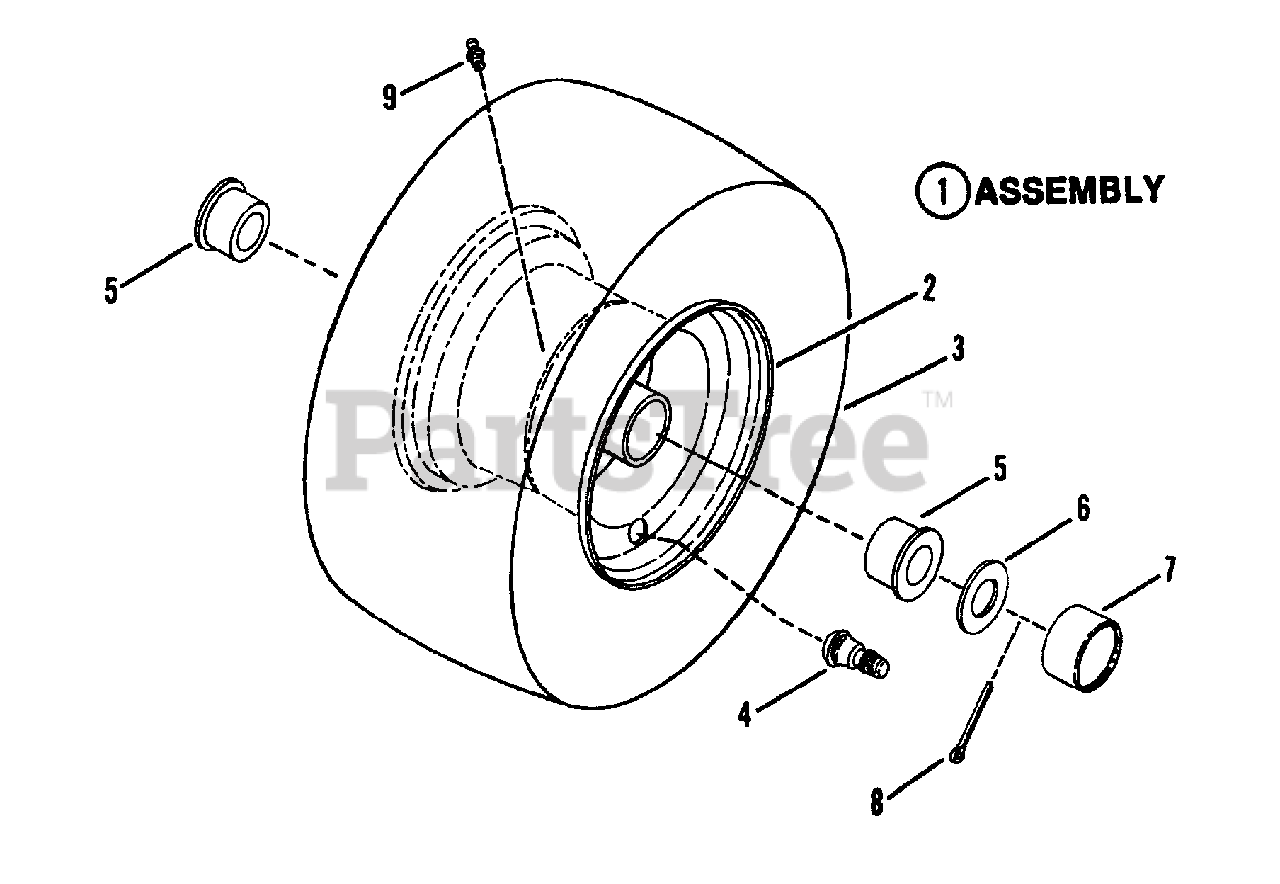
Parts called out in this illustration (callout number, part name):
1	ASSEMBLY, Front Tire & Rim
2	RIM, LT16 Front Wheel
3	TIRE, 15 x 6.00 x 6
4	VALVE, Air
5	BEARING, Wheel
6	WASHER, 49/64 x 1-1/2" Flat
7	COVER, Dust
8	PIN, 5/32 X 1" Cotter
9	FITTING, Lube 1/4-28 Tapered Thread
